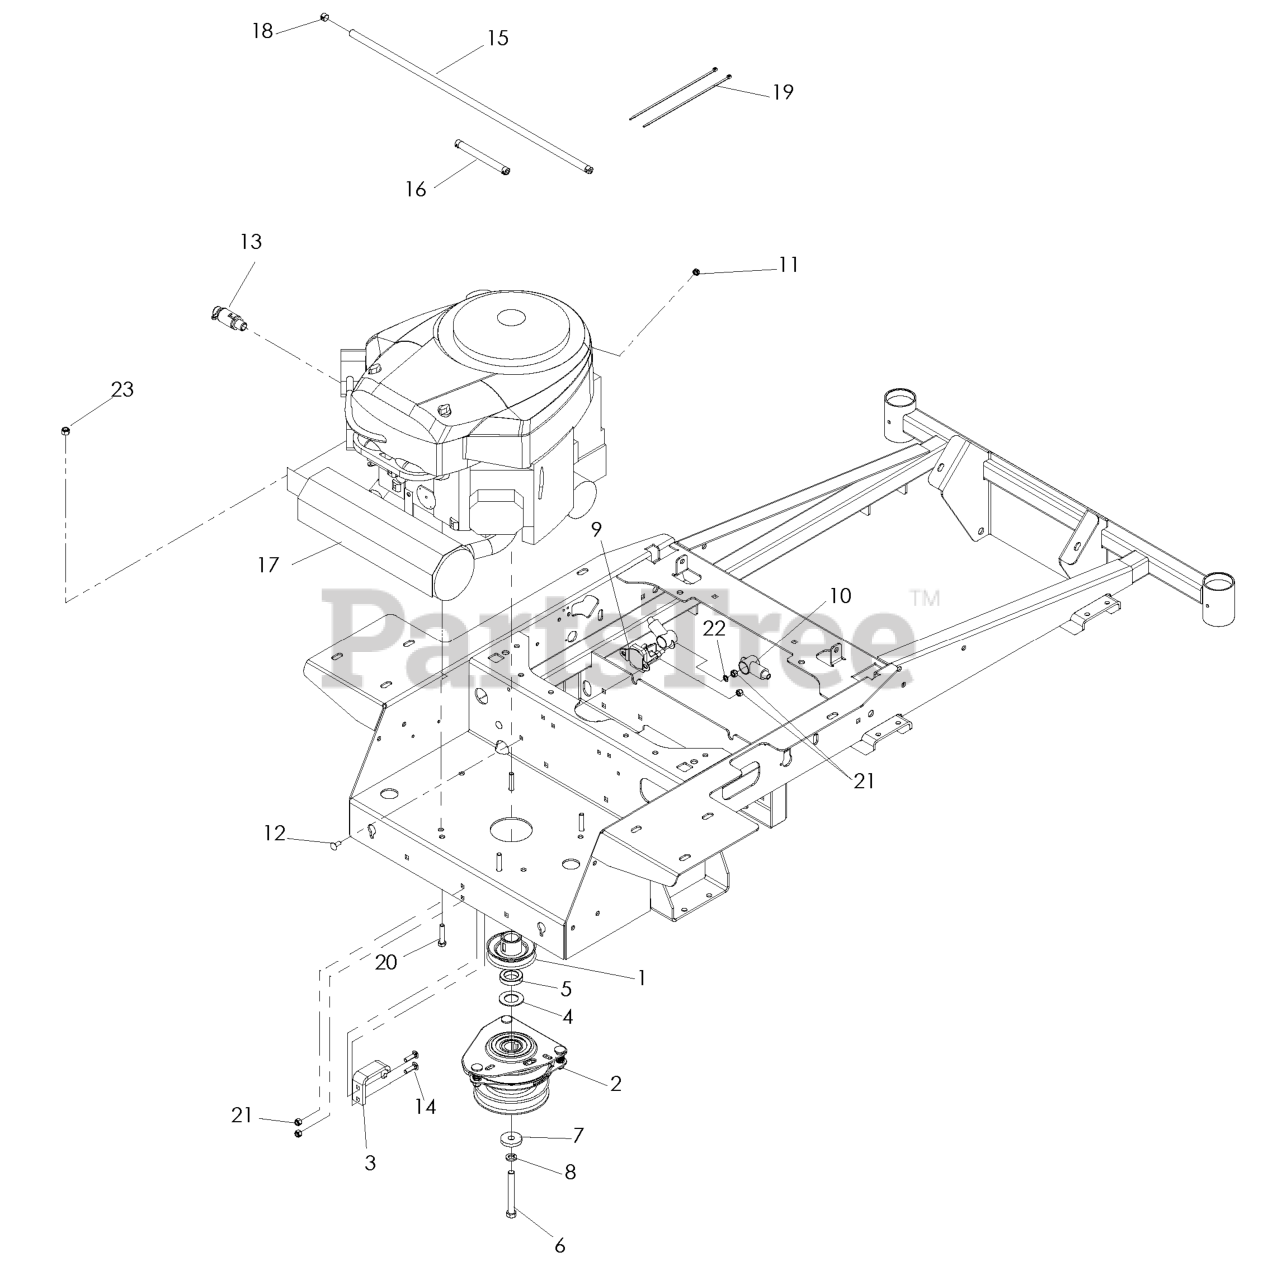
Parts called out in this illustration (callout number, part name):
1	PULLEY, ENGINE
2	CLUTCH, 90 FT/LBS
3	CLUTCH TIE DOWN
6	HCS 7/16-20X3-1/2 GR 5 ZN
7	CLUTCH, WASHER
8	WASHER 7/16 LOCK
11	JAM NUT 1/4C (2 2 PW01)
12	RHSSNB, 1/4-20X5/8
13	OIL DRAIN FITTING
14	RHSNB, 1/4-20 X 1, GR5
15	FUEL LINE 24"
16	FUEL LINE 5"
18	HOSE CLAMP
19	TIE, PLASTIC
20	CAPSCREW 5/16 X 1/1/2 HEX HEAD
21	NUT.1/4-20.HEX.NYLOC.ZD
22	WASHER 1/4 INT TOOTH
23	NUT 5/16 NYLOC
